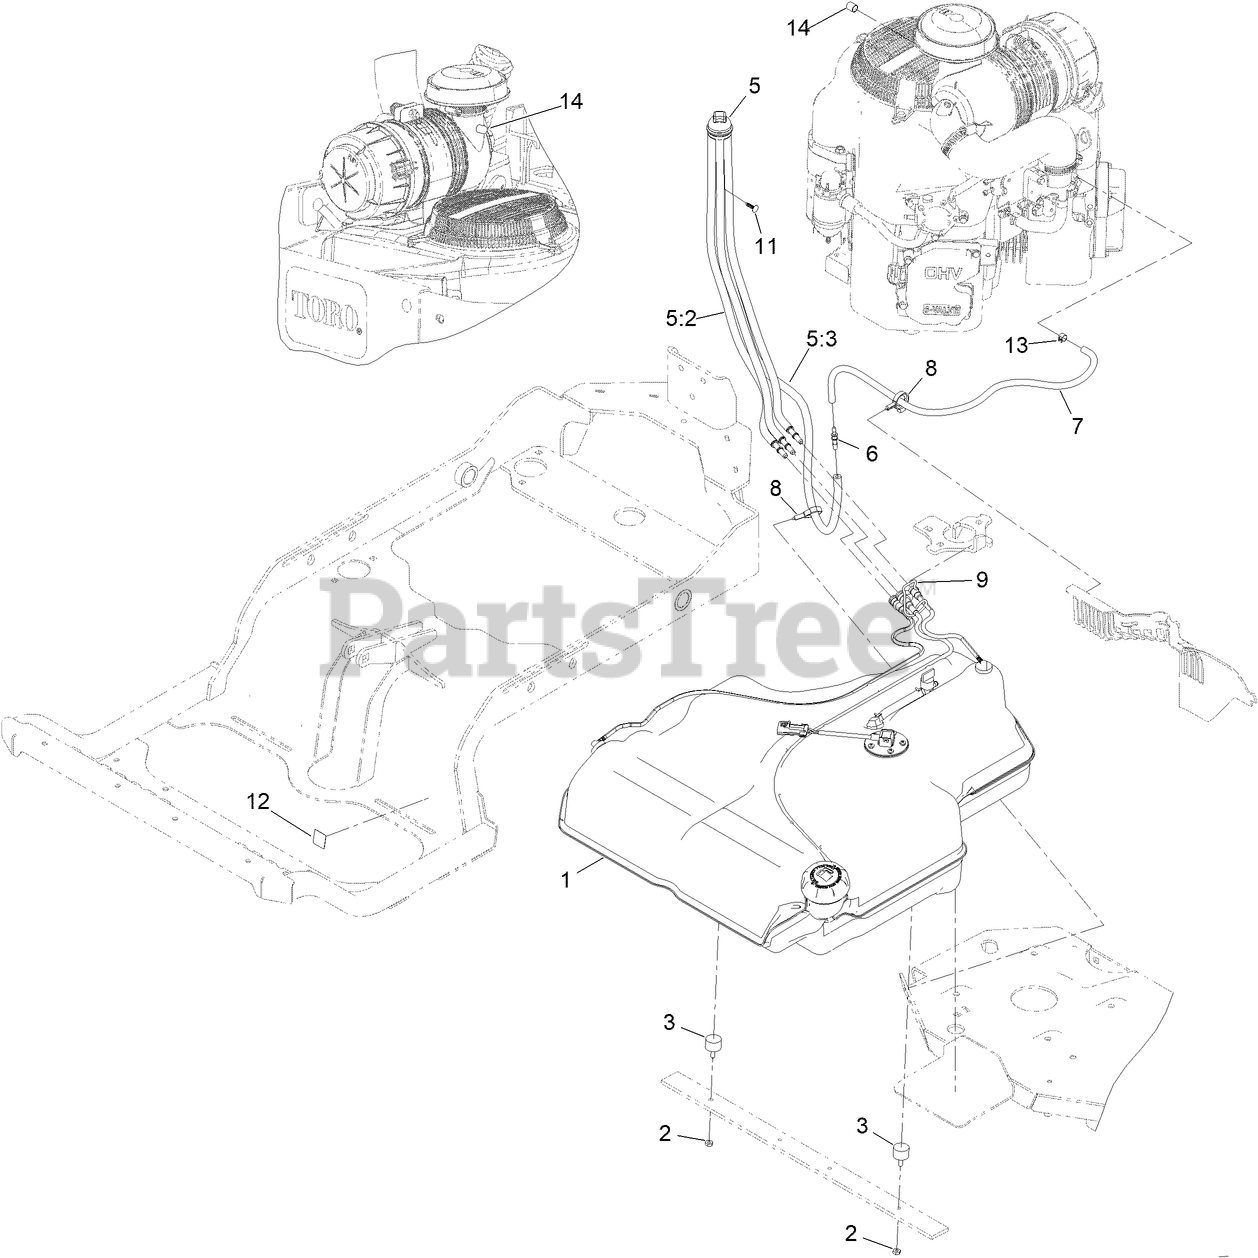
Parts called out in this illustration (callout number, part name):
1	FUEL TANK ASM
2	NUT-JAM
3	BUMPER
5	FUEL MANIFOLD VENT ASM
5:2	HOSE-FUEL
5:3	HOSE-FUEL
6	BARB-FUEL
7	HOSE-FUEL
8	CLAMP-HOSE
9	RETAINER-LINE, VAPOR
11	PLUG-PLASTIC
12	DECAL-RCM
13	CLAMP-HOSE
14	PLUG-PORT
